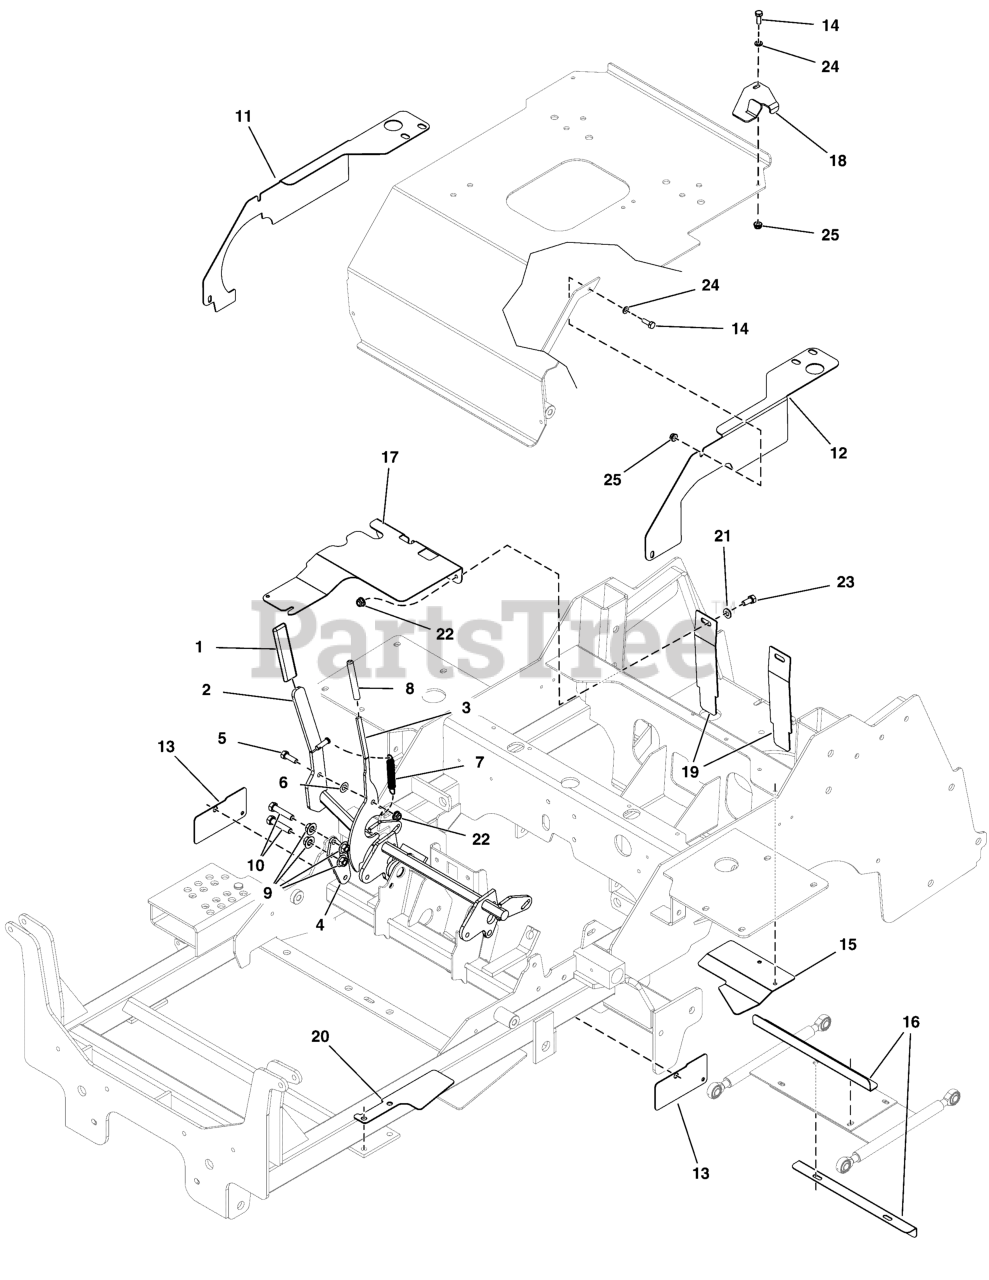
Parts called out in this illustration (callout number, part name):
1	GRIP, FOAM, 1/4 X 1 X 4.1
2	WELD, HANDLE, BRAKE, IS2100 CE - BLK
3	LEVER, BRAKE, IS2600 EU - BLK
4	PLATE, PIVOT MOUNT, BRAKE,IS2600 EU, RED
5	SCREW, TRUSS HD TORX DR5/16-18X0.875 BLK
6	WASHER,WAVE,M10
7	SPRING-EXT, .500 OD X 3.50 LG X .058 WR
8	COVER, VINYL HANDLE
9	NUT, 5/16-18 HEX SERRATED FLANGE (SMALL)
10	BOLT, 5/16-18 X 1-3/4" GD5 YZ
11	PLATE, GUARD, SEAT PLATFORM, RH - RED
12	PLATE, GUARD, SEAT PLATFORM, LH - RED
13	PLATE, CRADLE GUARD, CE - RED
14	BOLT, 1/4"-20 X 3/4" GD5 YZ
15	SHIELD, Debris
16	PLATE, GUARD, PULLER BAR,IS2600Z EU, BLK
17	COVER, Fan
19	PLATE, COVER, TRANSMISSION - BLK
20	PLATE, DECK SHIELD, FRAME - LH - RED
21	WASHER, 5/16" SAE
22	NUT, 5/16-18 HEX NYLOCK FLANGE NUT
23	BOLT, 5/16-18 X 3/4 GD5
24	WASHER, 1/4 SAE
25	NUT, 1/4-20 Hex Nylock Flange
